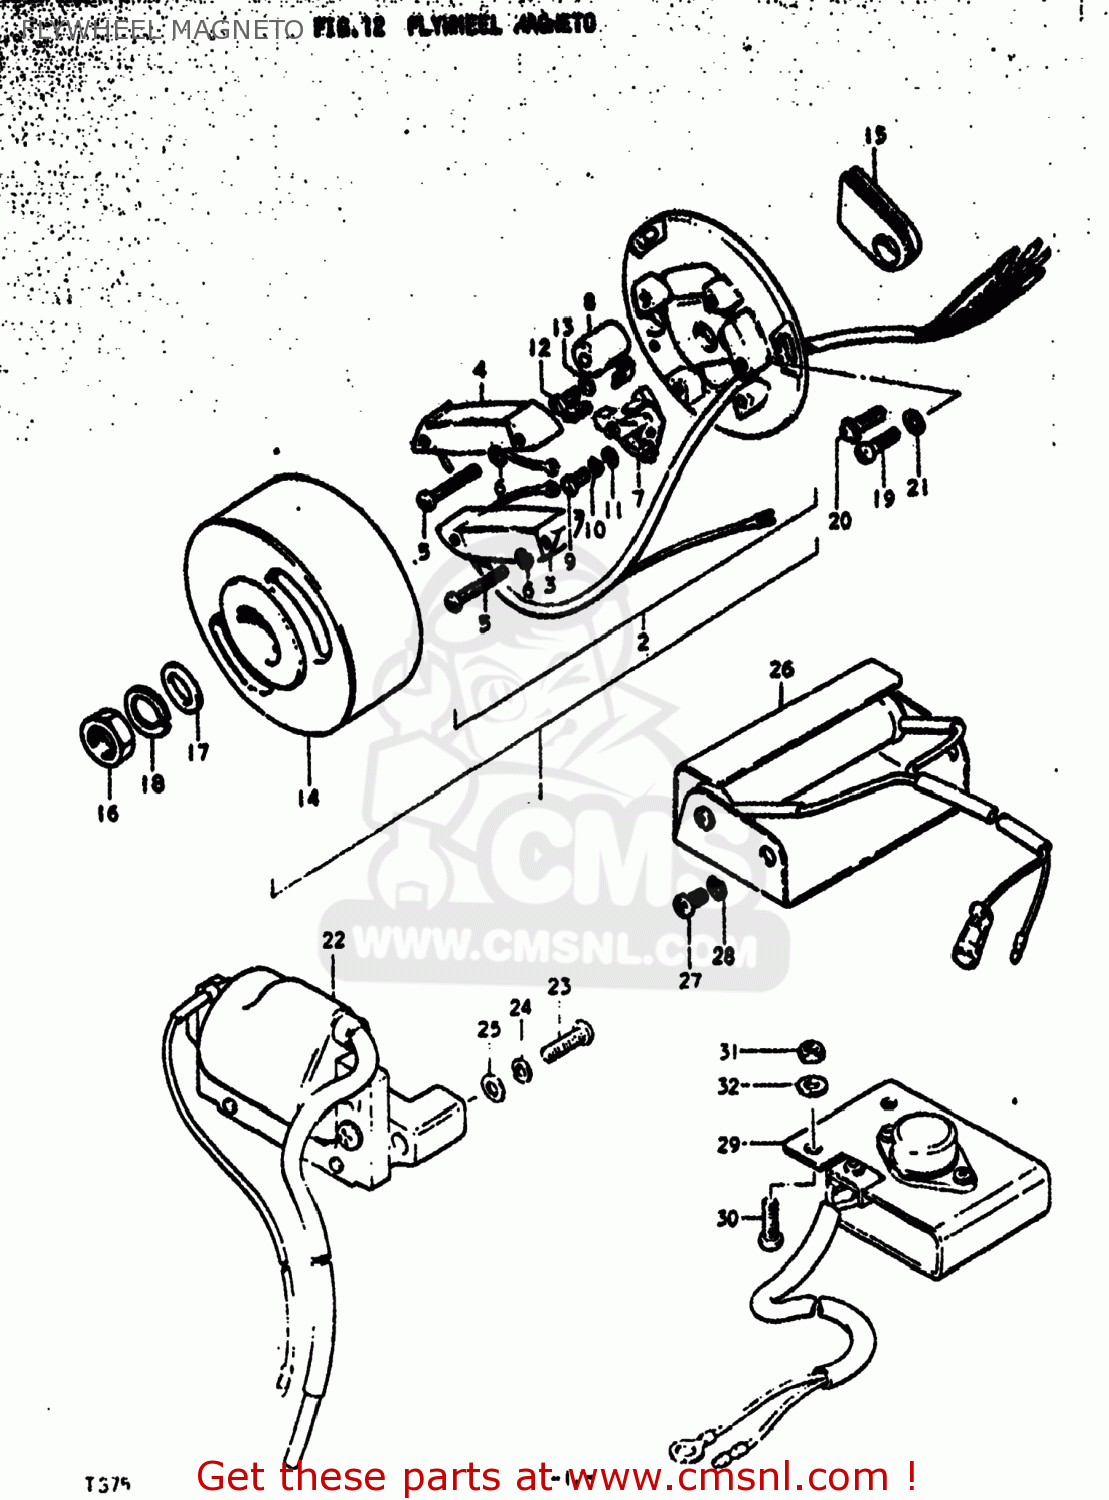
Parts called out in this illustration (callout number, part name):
1	MAGNETO ASSEMBLY
2	STATOR ASSEMBLY
3	COIL,LIGHTING
4	COIL
5	SCREW
6	LOCK WASHER
7	POINT ASSEMBLY,CONTACT
8	CONDENSER
9	.SCREW
10	LOCK WASHER
11	WASHER
12	SCREW
13	LOCK WASHER
14	ROTOR ASSEMBLY
15	GROMMET
16	NUT
17	WASHER
18	LOCK WASHER
19	SCREW
20	SCREW(5X14)
21	WASHER
22	COIL ASSEMBLY,IGNITION
23	Screw
24	LOCK WASHER
25	WASHER
26	MAGNETO RESISTOR ASS
27	SCREW
28	LOCK WASHER
29	REGULATOR ASSEMBLY
30	SCREW 6X12
31	NUT
32	WASHER
